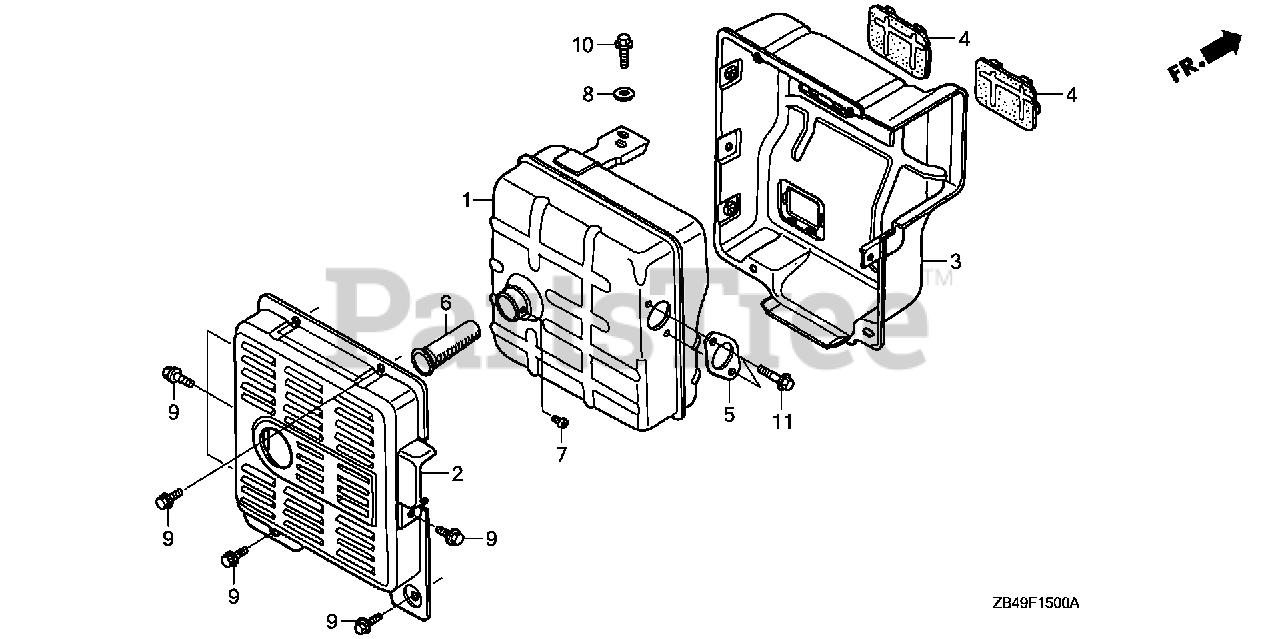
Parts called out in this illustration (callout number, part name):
1	MUFFLER (SANKEI)
2	PROTECTOR, MUFFLER (OUTER)
3	PROTECTOR, MUFFLER (INNER)
4	SEAL, MUFFLER PROTECTOR
5	GASKET, EX. PIPE
6	ARRESTER, SPARK
7	SCREW, TAPPING (4X8)
8	WASHER, PLAIN (8MM)
9	BOLT, FLANGE (6X10)
10	BOLT, FLANGE (8X16)
11	BOLT, FLANGE (8X20)
